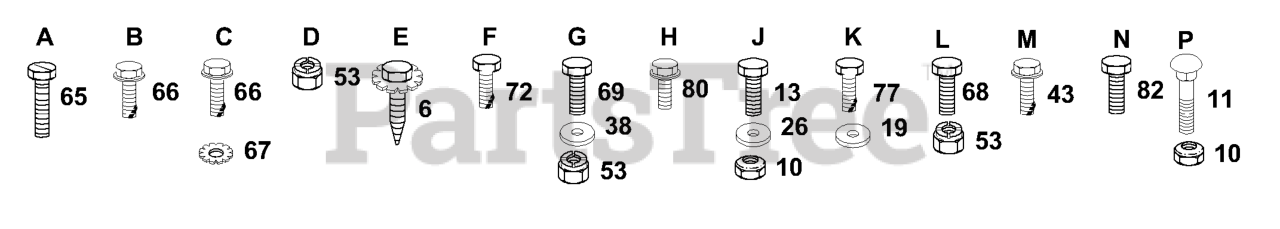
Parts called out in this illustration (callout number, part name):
6	Screw, Spider Lock, Hex #8 x 1/2
10	LOCKNUT
11	RP BOLT 5/16-18 X3/4 ZN/YEL GR
13	BOLT RB
19	WASHER
38	WASHER
65	SCREW LT
66	SCREW LT
67	LOCKWASHER
69	BOLT
72	SCREW
77	SCREW.THDROL.5/16-18X3/4.TTY
80	SCREW
82	Bolt, Metric
